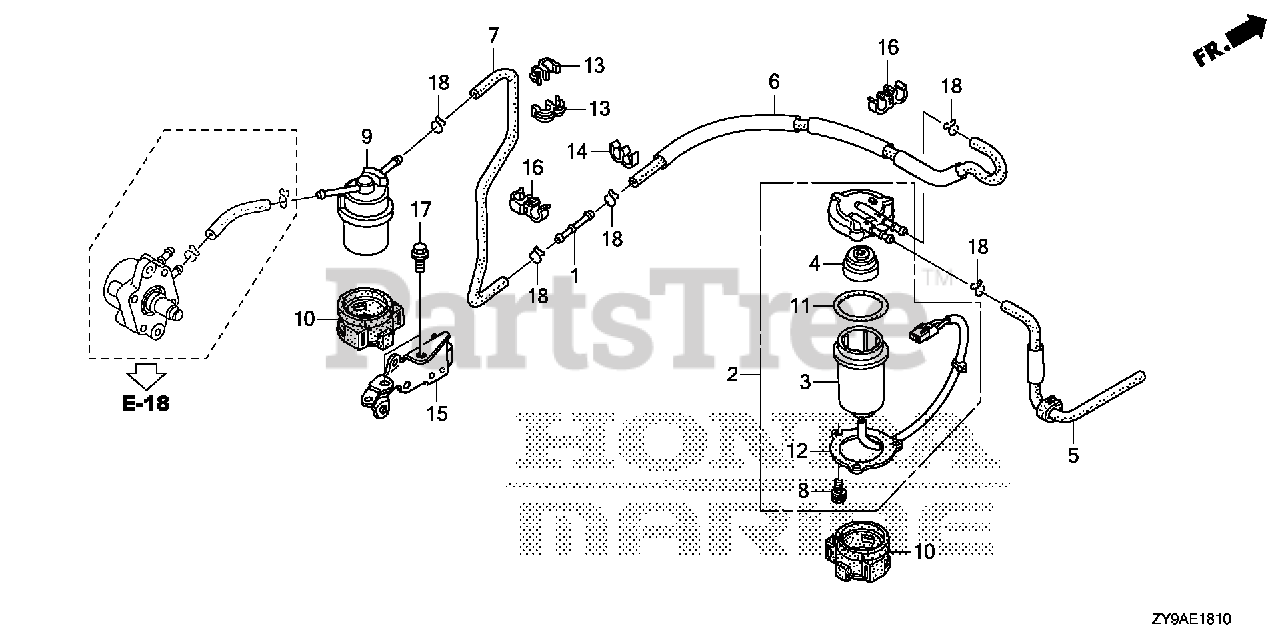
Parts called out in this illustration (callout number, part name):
1	JOINT, FUEL FEED HOSE
2	SEPARATOR ASSY., WATER
3	CUP, WATER SEPARATOR
4	BUFFER, PLATE
5	TUBE A, FUEL
6	TUBE B, FUEL
7	TUBE C, FUEL
8	SCREW, PAN (5X12)
9	FILTER, FUEL
10	SUSPENSION, STRAINER
13	CLAMP, TUBE (7.5-11.5) (BLACK)
14	CLAMP, TUBE
15	BRACKET B, HARNESS CLIP
16	CLIP, SENSOR HOSE
17	BOLT, FLANGE (6X14) (CT200)
18	CLIP, TUBE (B12)
